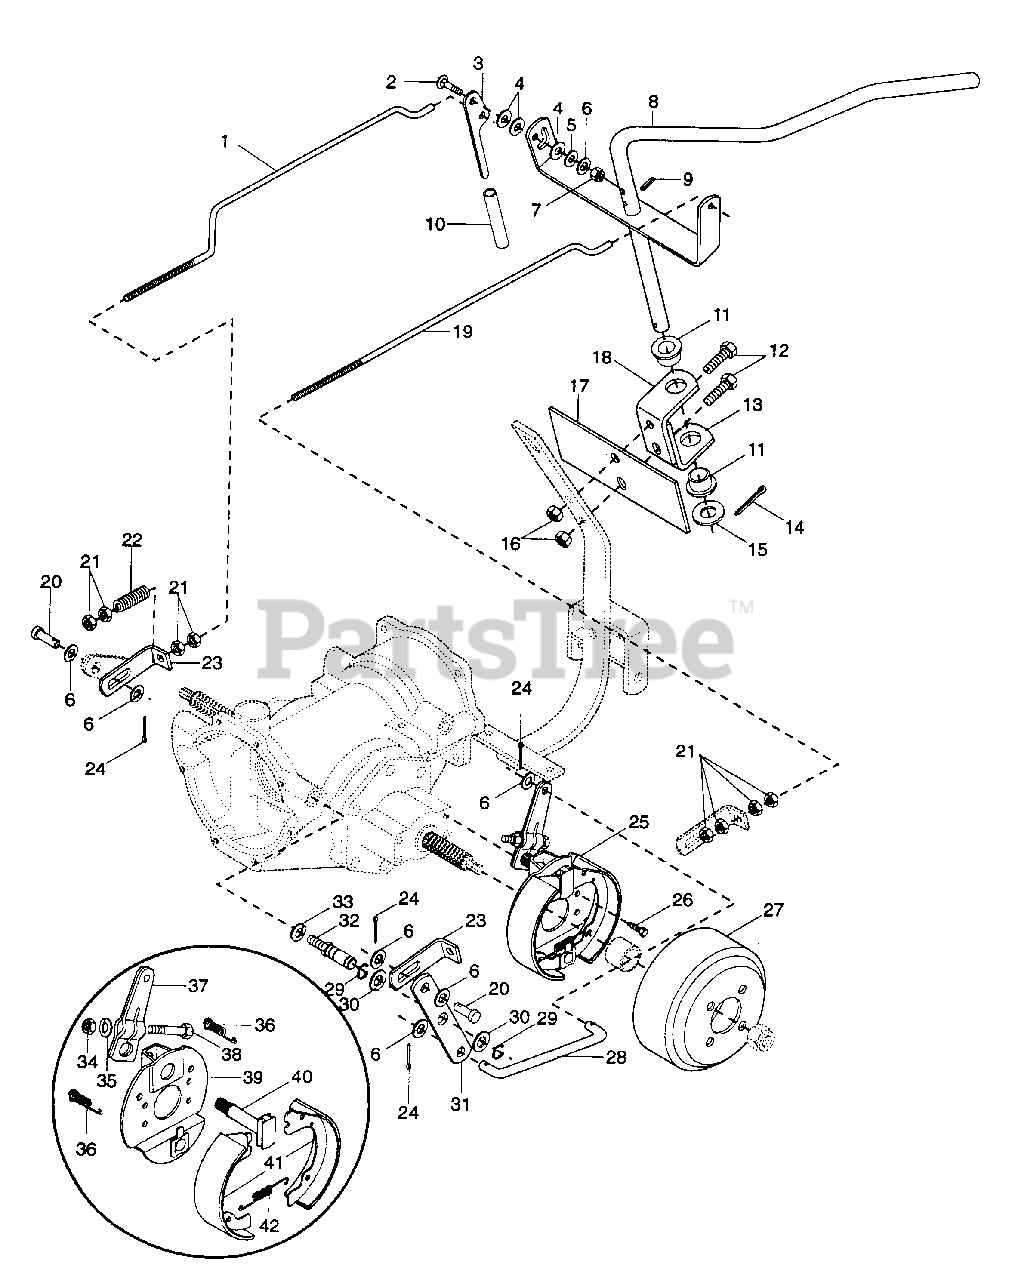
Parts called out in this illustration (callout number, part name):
1	ROD, BRAKE
1	ROD, BRAKE R.H.
2	BLT-RDHDSQNK .38-16 X 1.50
3	HNDL, PARKING BRAKE
4	WSHR-FL-NY .375 X .75 X .060
5	WSHR-RUBBER .375 X .75 X .125
6	WSHR-FL-STL .406 X .812 X .065 PL
7	NUT-LK-NYL .375-16 PL
8	WLDMT, BRAKE HANDLE
9	PIN-ROLL .313 X 2.00
10	GRIP, BRAKE HANDLE
11	BSHG-FLG 1.082 X 1.385 X .870 X 1.75
12	BLT-HEX .50-13 X 2.00 PL GR 5
13	BRKT, BRAKE HANDLE
14	PIN-COTR .188 X 1.50
15	WSHR-FL-STL 1.120 X 1.500 X .092
16	NUT-LK-NYL .50-13 PL
17	PLT, INSTRUCTION
18	BRKT, BRAKE HANDLE
19	ROD, BRAKE L.H.
20	PIN, CLEVIS 3/8 X .750
21	NUT-JAM .375-16 PL
22	SG-COMP .105 X .61 X 2.50 WLD 180
23	BRKT, ADJUSTMENT
24	PIN-COTR .09 X .75 PL
25	BRK, 7 X 1-3/4 MECHANICAL
26	BLT-HEX .380-16 X .875
27	DRUM, 7 X 1-3/4
28	ROD, BRAKE LINK
29	RG-RTNG-EXT .480 X .042
30	WSHR-FL-STL .656 X 1.312 X .095 PL
31	PLT, PIVOT
32	STUD, PIVOT
33	WSHR-LOCK .50 REG
34	NUT-HEX .312-24 ZC
35	WSHR-LOCK .313 X .078 PL
36	SPRG, SHOE RET BOX
37	ARM, CAM LVR
38	BLT-HEX .31-24 X 1.75
39	PLT, BACK(BENDIX # 310949)
40	CAM, BRAKE
41	KIT, PAIR BRAKE SHOES(BEN 317974)
42	SPRG, SHOE RTN
